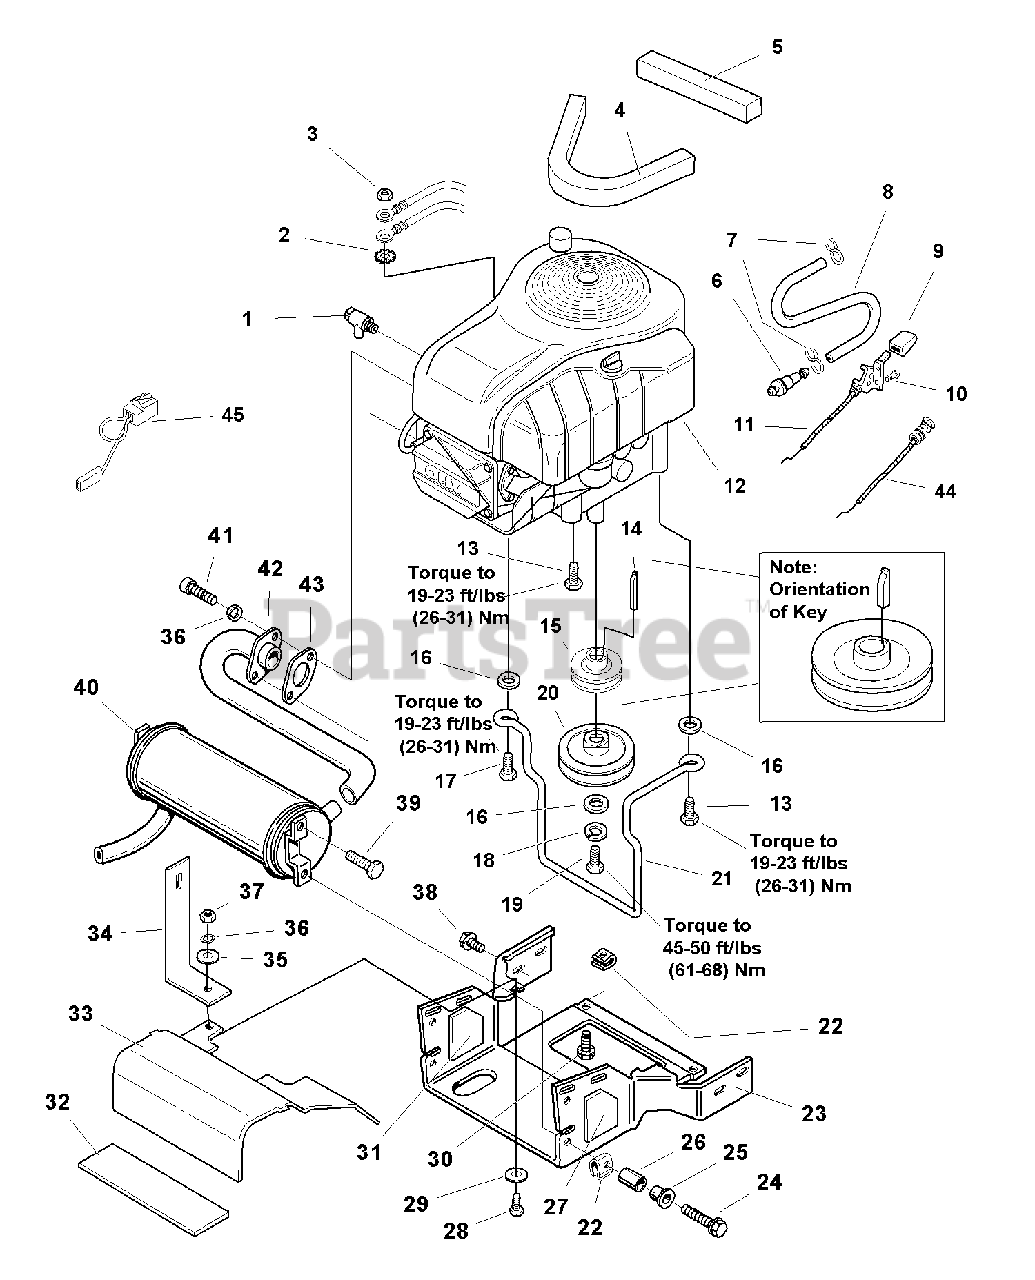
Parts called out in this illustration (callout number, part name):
1	VALVE-SHUT OFF
2	LOCKWASHER, External Tooth 3/8
3	NUT, Hex 3/8-16
4	SEAL, Foam
6	FILTER, Fuel
7	CLAMP, Hose Type E
8	HOSE, 12" Long
10	CAPSCREW, Hex Washer Head 1/4-14 x 5/8
11	CABLE, Throttle Control, 14~ Long
12	ENGINE-15/16/17HP Briggs & Stratton INTEK SINGLE
13	CAPSCREW, Hex Washer Head, Taptite, 3/8-16 x 1-1/2
14	KEY, Hi-Pro
15	PULLEY, Hydro Only
16	WASHER
17	CAPSCREW, Hex Washer Head, Taptite, 3/8-16 x 2
18	LOCKWASHER, 7/16
19	CAPSCREW, 7/16-20 x 2
20	PULLEY, 5.40 O.D.
22	NUT, Speed 5/16-18
23	DUCT, Muffler
24	CAPSCREW, Hex Flange Lock, 5/16-18 x 1-1/4
27	INSULATION, LH
28	CAPSCREW, 5/16-18 X 1
29	WASHER
30	CAPSCREW, Hex Flange Lock, 5/16-18 x 3/4
31	INSULATION, RH
33	DUCT,Muffler, Upper
34	STRAP, Torque
36	LOCKWASHER, 5/16
37	NUT, Hex 5/16-18
38	CAPSCREW, Hex Washer Head, Taptite, 5/16-18 x 1/2
39	CAPSCREW, Hex Washer Head, Taptite, 1/4-20 x 3/8
41	CAPSCREW, 5/16-18 x 3/4, G8
42	PIPE, Exhaust
44	CABLE, Choke, 16" Long
45	WIRE ASSEMBLY, Briggs & Stratton Export
